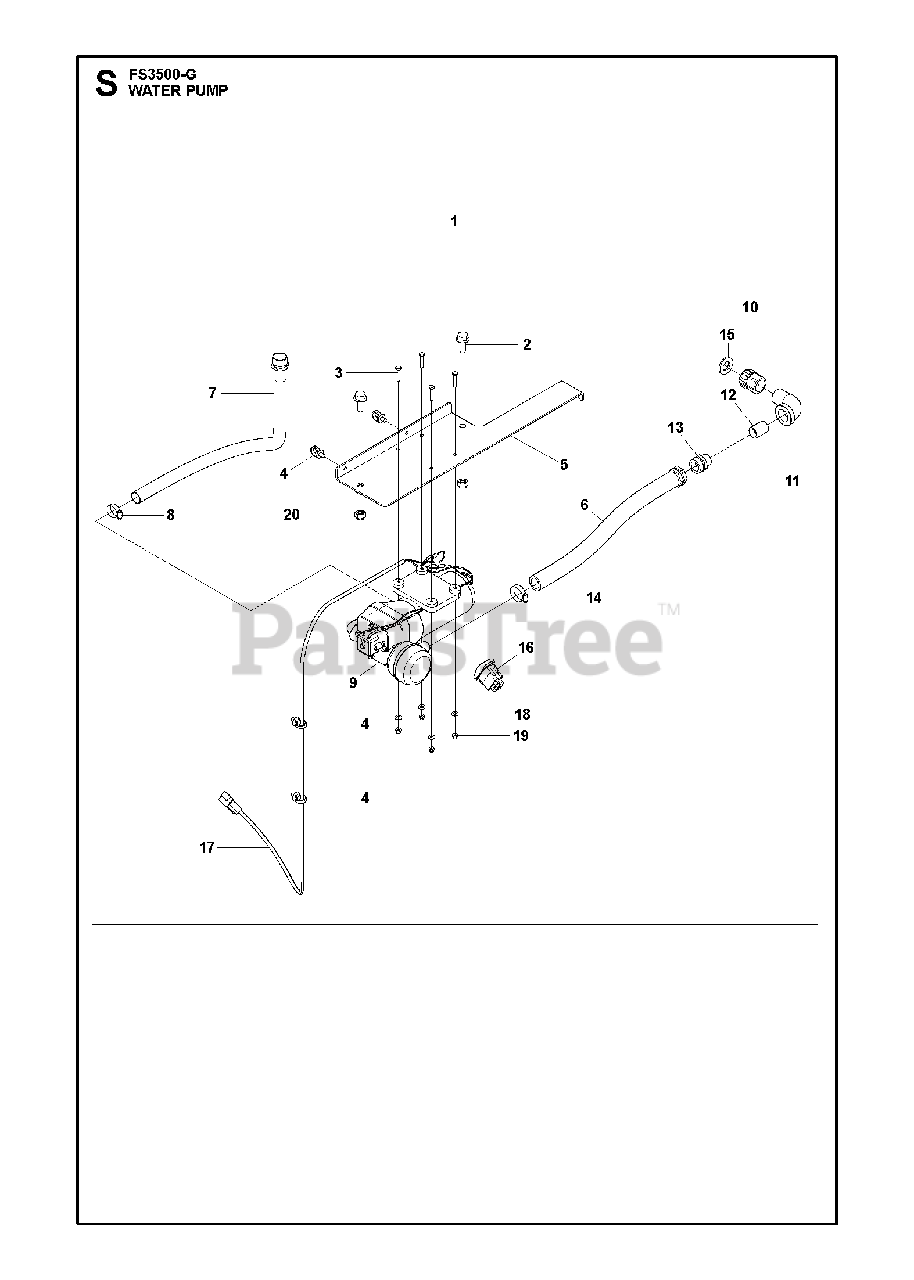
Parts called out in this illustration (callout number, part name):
18	WASHER
19	HEXAGON LOCKING NUT
20	HEXAGON LOCKING NUT
